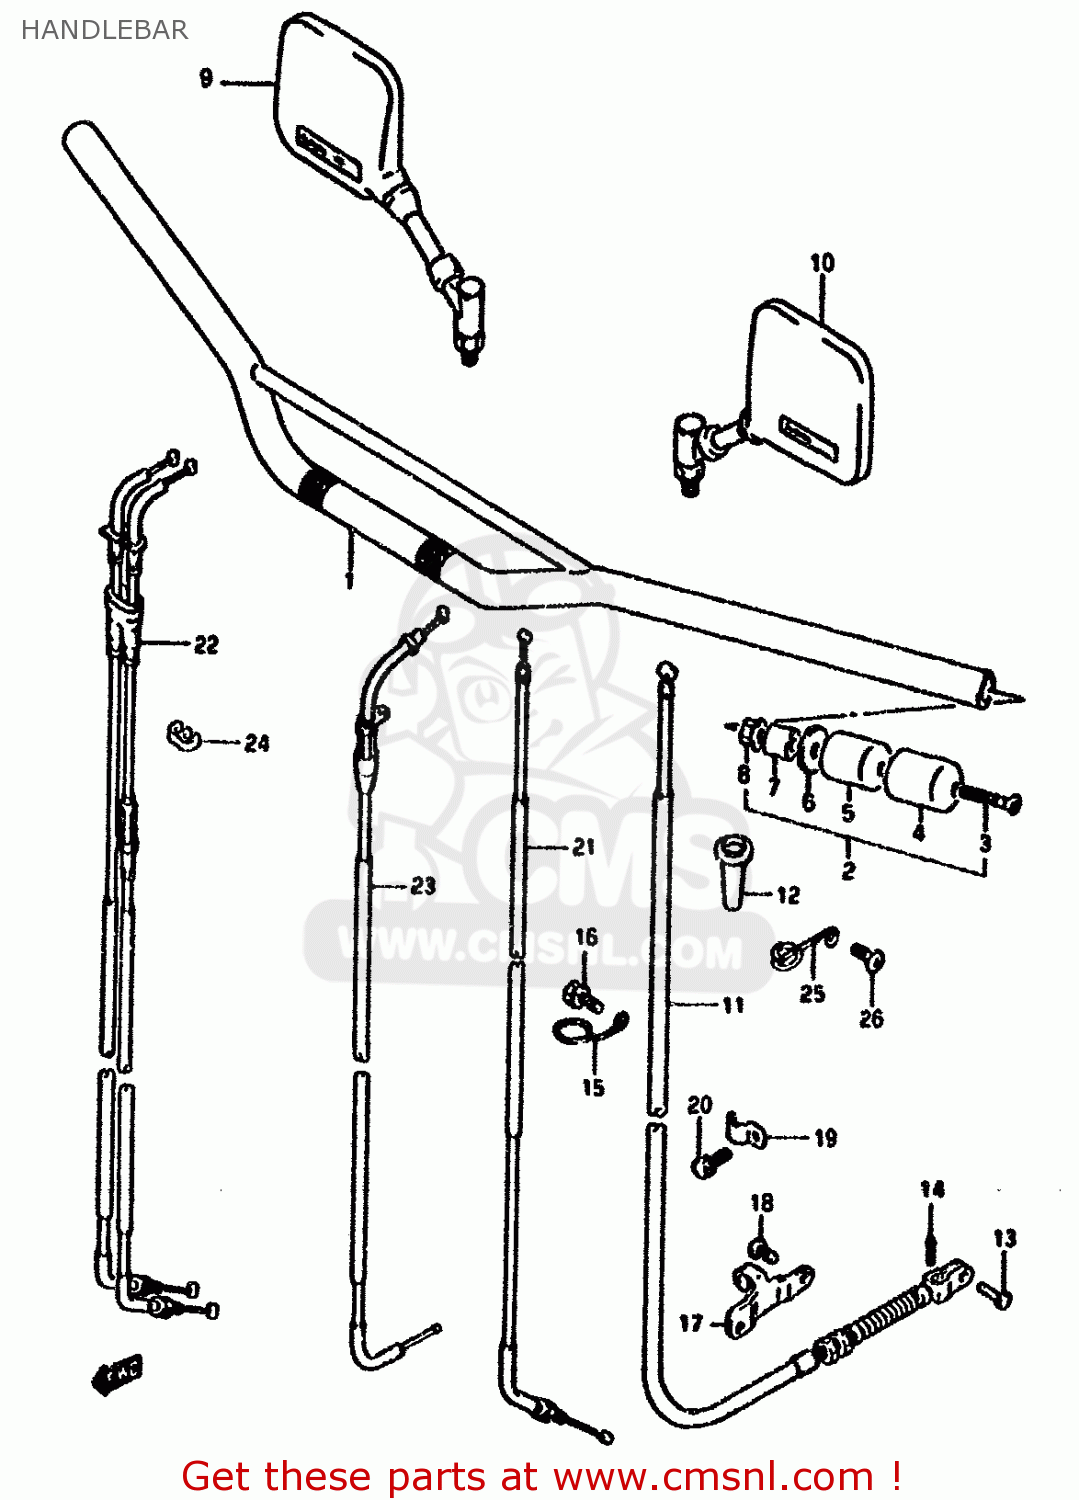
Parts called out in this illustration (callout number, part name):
1	HANDLEBAR
2	BALANCER SET,HANDLEBAR
3	SCREW
4	CAP,BALANCER
5	BALANCER,HANDLE
6	SPACER,BALANCER
7	EXPANDER,HANDLE BALANCER
8	NUT
9	MIRROR ASSY,RR VIEW,R
10	MIRROR ASSY,RE
11	CABLE ASSY,CLUTCH
12	BOOT,CLUTCH CABLE
13	PIN(L:13)
14	PIN
15	GUIDE
16	BOLT
17	STOPPER,CLUTCH CABLE
18	SCREW
19	CLAMP
20	BOLT
21	CABLE ASSY,DECOMP
22	CABLE ASSY,THROTTLE
23	CABLE,STARTER
24	CLIP
25	GUIDE,CLUTCH CABLE
26	SCREW
